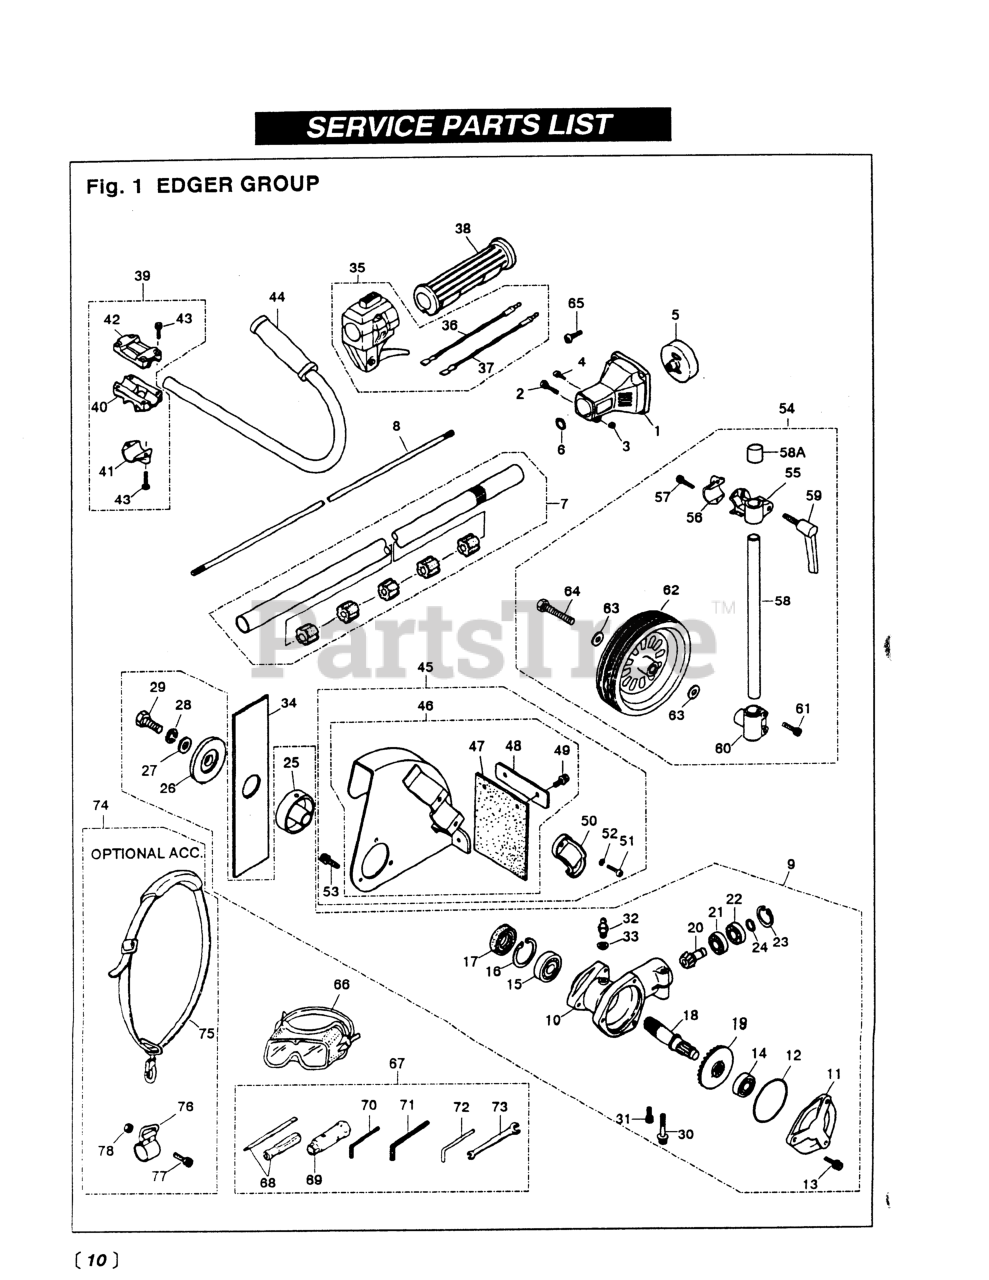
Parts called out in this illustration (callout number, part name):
1	HOUSING (NO LONGER AVAILABLE)
2	BOLT, M6x35 (RPLS -50635)
3	NUT, M6 X 5
4	SCREW, M6 X 14
6	RING, SNAP
7	PIPE COMPLETE
11	COVER
12	O-RING
13	BOLT
14	BEARING (RPLS T3403-13510)
16	RING, SNAP, M32 x 1.2
17	SEAL, OIL
18	SHAFT, GEAR
19	GEAR
20	PINION
21	BEARING (RPLS T3403-13530)
22	BEARING (RPLS T3300-13531)
23	RING, SNAP, M24 x 1.2
24	RING, SNAP (RPLS T3300-13330)
25	HOLDER (A)
26	HOLDER (B)
27	WASHER, M8 x 2.3 (RPLS -20823)
28	WASHER (RPLS 3180-13270)
29	BOLT, LH
30	BOLT, M6 x 1.35
31	BOLT, M5 x 12
32	FITTING, GREASE
33	WASHER, M6 X .8
34	BLADE, EDGER (RPLS 147315)
35	LEVER ASSEMBLY
36	CORD-A, BLACK
37	CORD-B, RED
39	BRACKET (USE 3583-14101)
41	CAP, LOWER
43	BOLT, M5 X 22
44	HANDLE, J
47	PLATE (RUBBER)
49	BOLT, M5 X 12
51	BOLT, M6 X 18
52	WASHER, M6 X 15
53	BOLT
54	USE T3052-25001
55	BRACKET
56	CAP, LOWER
57	BOLT, M5 X 22
58	PIPE
59	LEVER
61	BOLT, M6 X 25
62	WHEEL
63	WASHER, M10 x 1.6
64	BOLT, M10 X 60
67	TOOL SET
68	SCREWDRIVER
70	WRENCH (TOOL)
71	WRENCH (TOOL)
72	BAR
73	SPANNER, 8 X 10 (RPLS 2540- )
74	STRAP KIT
76	HANGER COMP
77	BOLT, M5 X 10
78	NUT, M5 X 4
